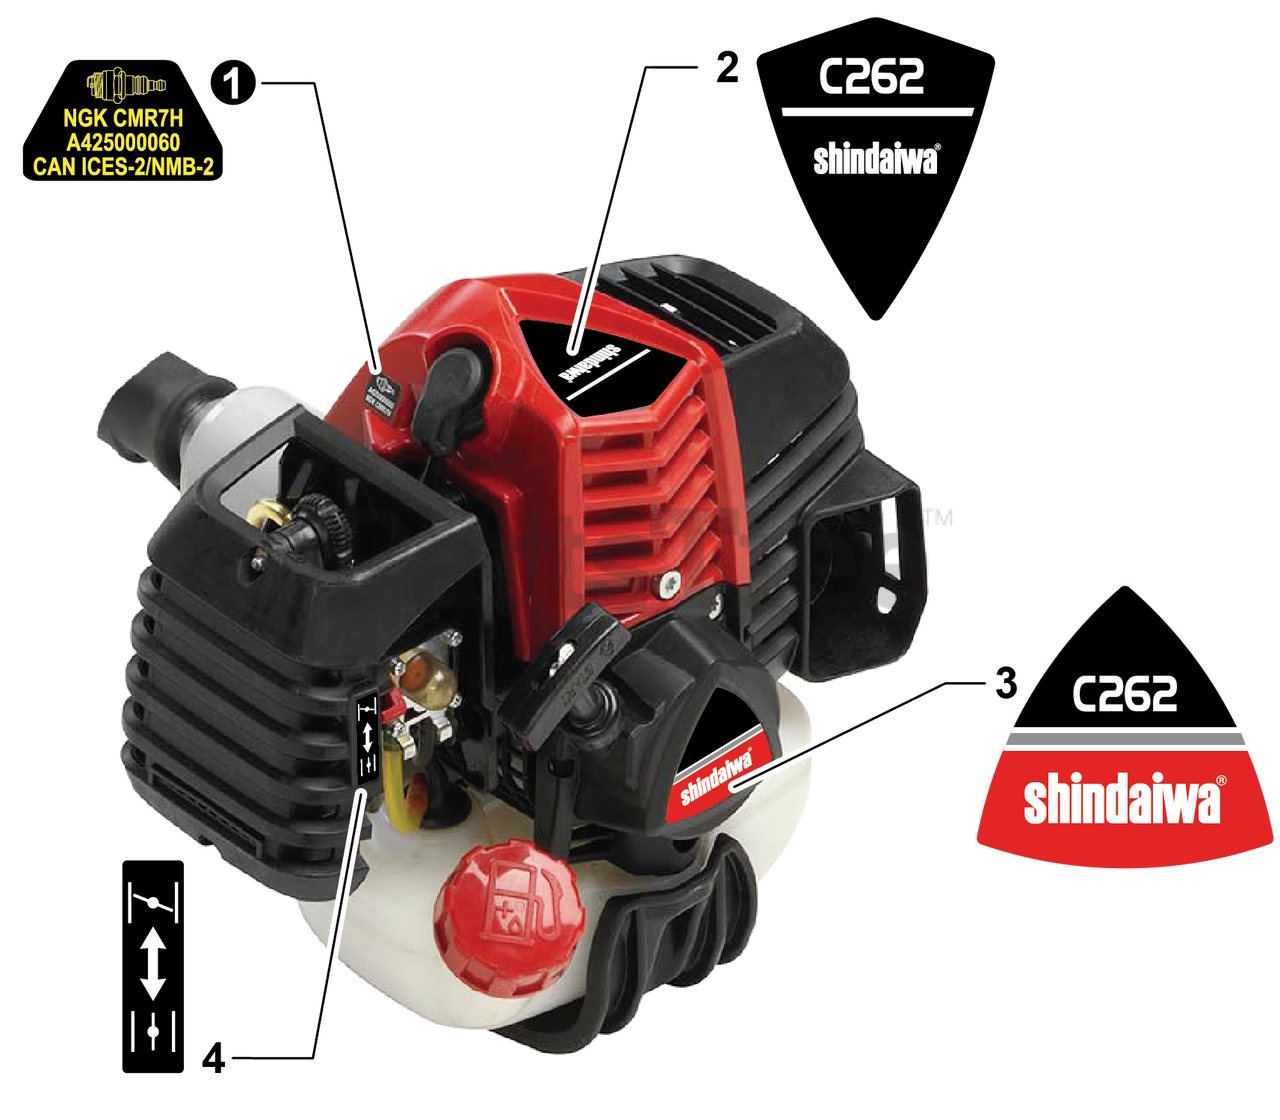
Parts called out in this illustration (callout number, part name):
1	LABEL, SPARK PLUG - CMR7H
2	LABEL - MODEL C262
3	LABEL, RECOIL STARTER
4	LABEL, CHOKE
